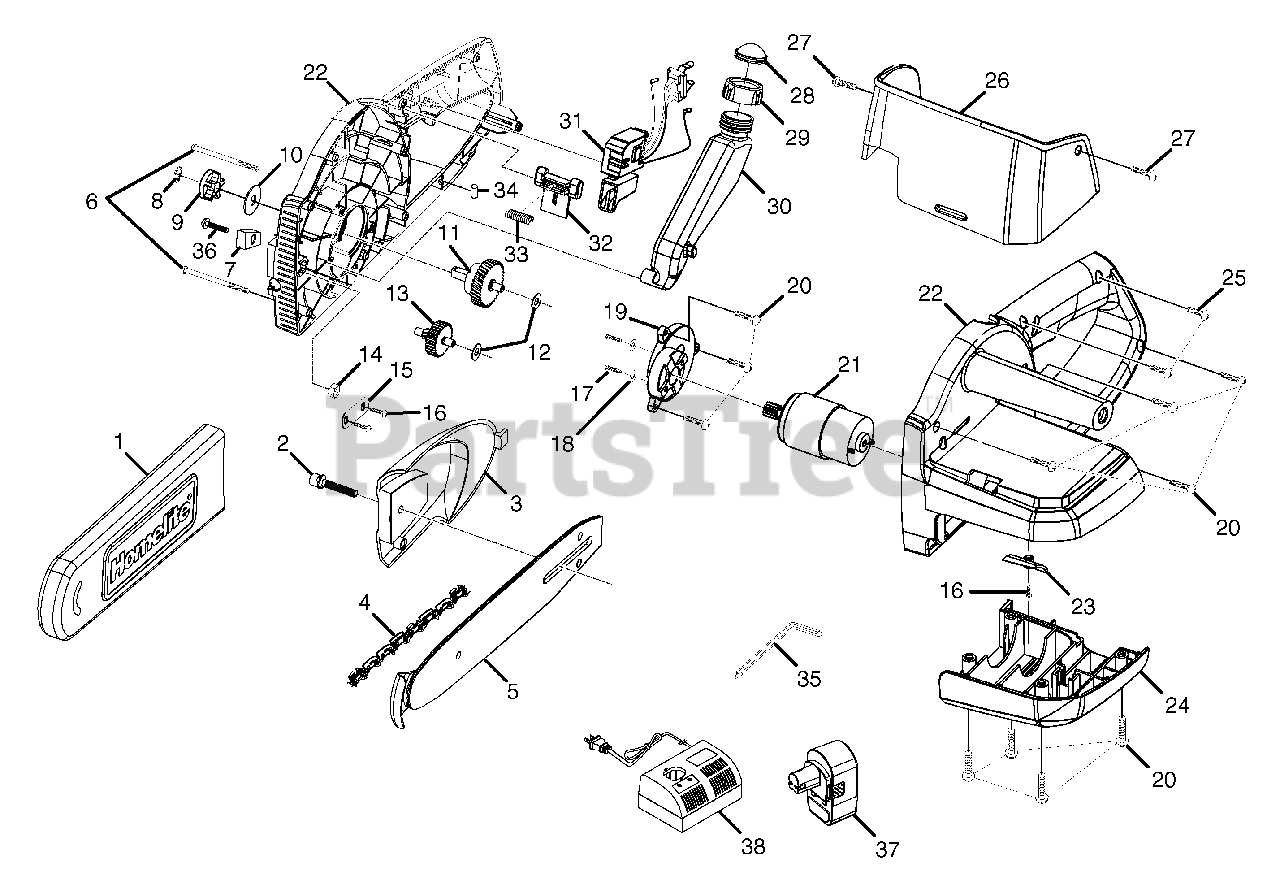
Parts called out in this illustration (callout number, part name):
1	GUARD
3	SPROCKET GUARD
4	CHAIN, (90JG-040)
5	CHAIN BAR (10 in)
6	SCREW (M4 X 66 mm)
7	FELT SEAL
9	SPROCKET
10	COVER PLATE
11	OUTPUT SHAFT ASSEMBLY
13	OUTPUT SHAFT ASSEMBLY
14	NUT (M6)
15	STEEL PLATE
16	BEARING RETAINER SCREW
17	SCREW (M4 X 12 mm)
18	SPRING WASHER
19	MOTOR MOUNTING ASSEMBLY
20	SCREW (M4 X 22 mm PAN HD)
21	MOTOR ASSEMBLY
22	MOTOR HOUSING SUPPORT
23	WIND PLATE
24	LOWER MOTOR HOUSING
25	SCREW (M4 X 16 mm PAN HD)
26	FRONT HANDLE GUARD W/LABELS
27	SCREW (M35 X 25 mm)
28	PRIMER BULB
29	SCREW CAP
30	OIL TANK
31	SWITCH ASSEMBLY
32	SAFETY KNOB
34	CONTACT PLATE STOPPER
35	HEX KEY (5mm)
36	SCREW (M23 X 6 mm)
38	BATTERY CHARGER
